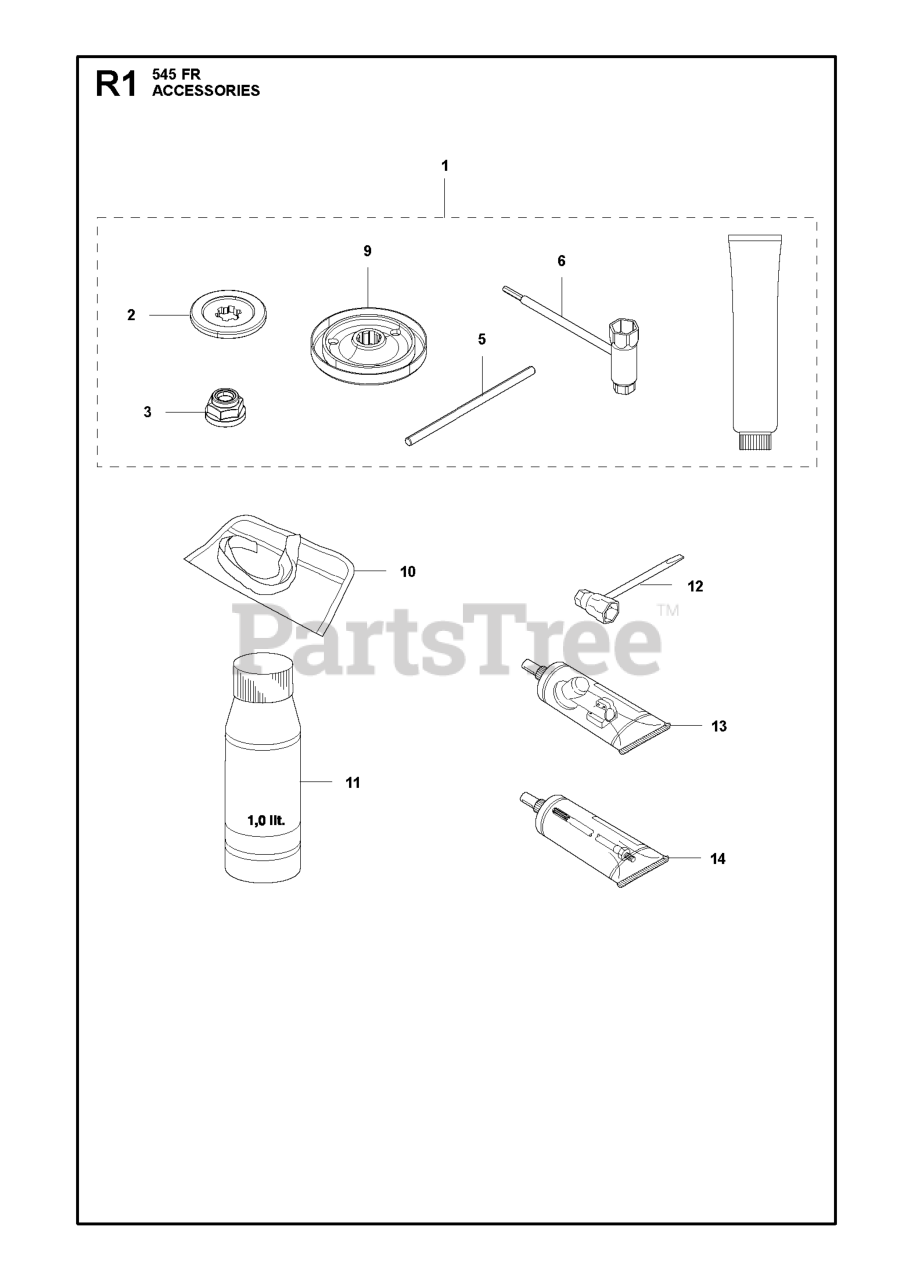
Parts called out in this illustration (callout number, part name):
1	ACCESSORY BAG
5	LOCKING PIN
6	COMBINATION WRENCH
11	Air Filter Oil 1l.
12	RP COMBI TOOL
13	BEVEL GEAR GREASE
14	DRIVE SHAFT GREASE (200 G)
